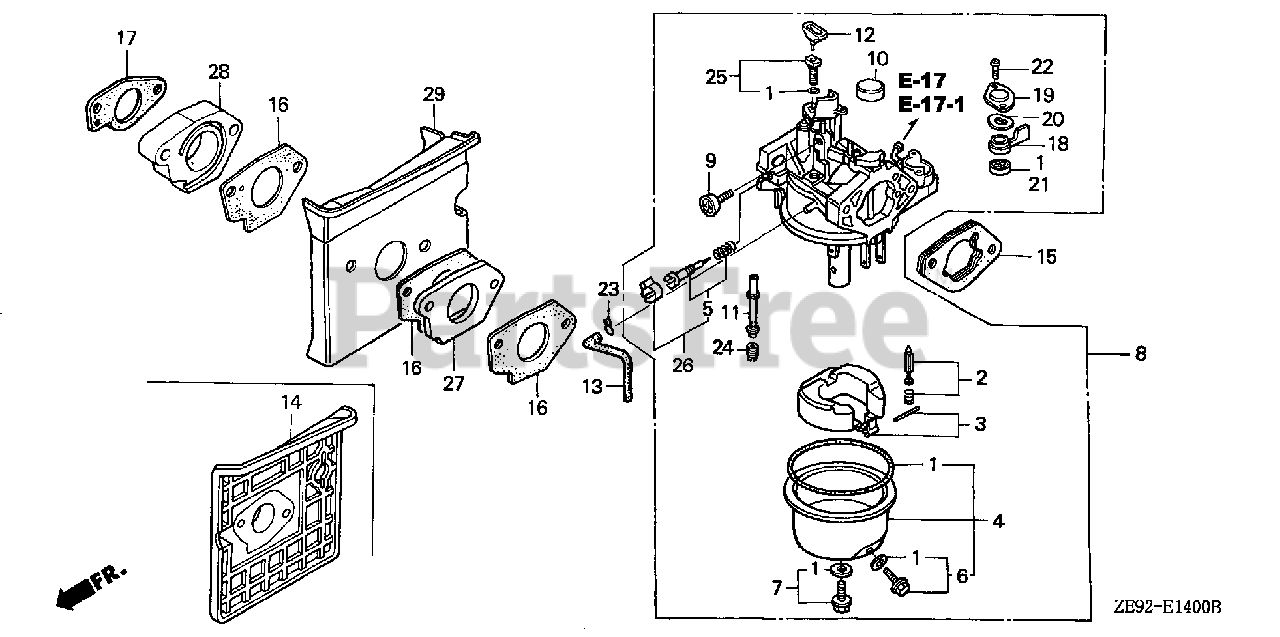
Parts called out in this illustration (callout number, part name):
1	GASKET SET (EXC. 16173-001-004) (EXCEPT 16173-001-004)
2	VALVE SET, FLOAT
4	CHAMBER SET, FLOAT
6	SCREW SET, DRAIN
7	SCREW SET
8	CARBURETOR ASSY. (BE81A C)
9	SCREW, THROTTLE STOP
10	CAP, CHOKE DUST
11	NOZZLE, MAIN
12	COLLAR, SETTING
13	TUBE, AIR VENT (75MM)
14	INSULATOR, CARBURETOR
15	SPACER, CARBURETOR
16	GASKET, CARBURETOR
17	GASKET, INSULATOR
18	LEVER, PETCOCK
19	PLATE, LEVER SETTING
20	SPRING, PETCOCK LEVER
21	GASKET, PETCOCK
22	SCREW, PAN (3X6)
23	CLIP, TUBE (B8)
24	JET, MAIN (#88)
24	JET, MAIN (#90)
24	JET, MAIN (#92)
25	JET SET, PILOT (#38)
26	SCREW SET, PILOT
